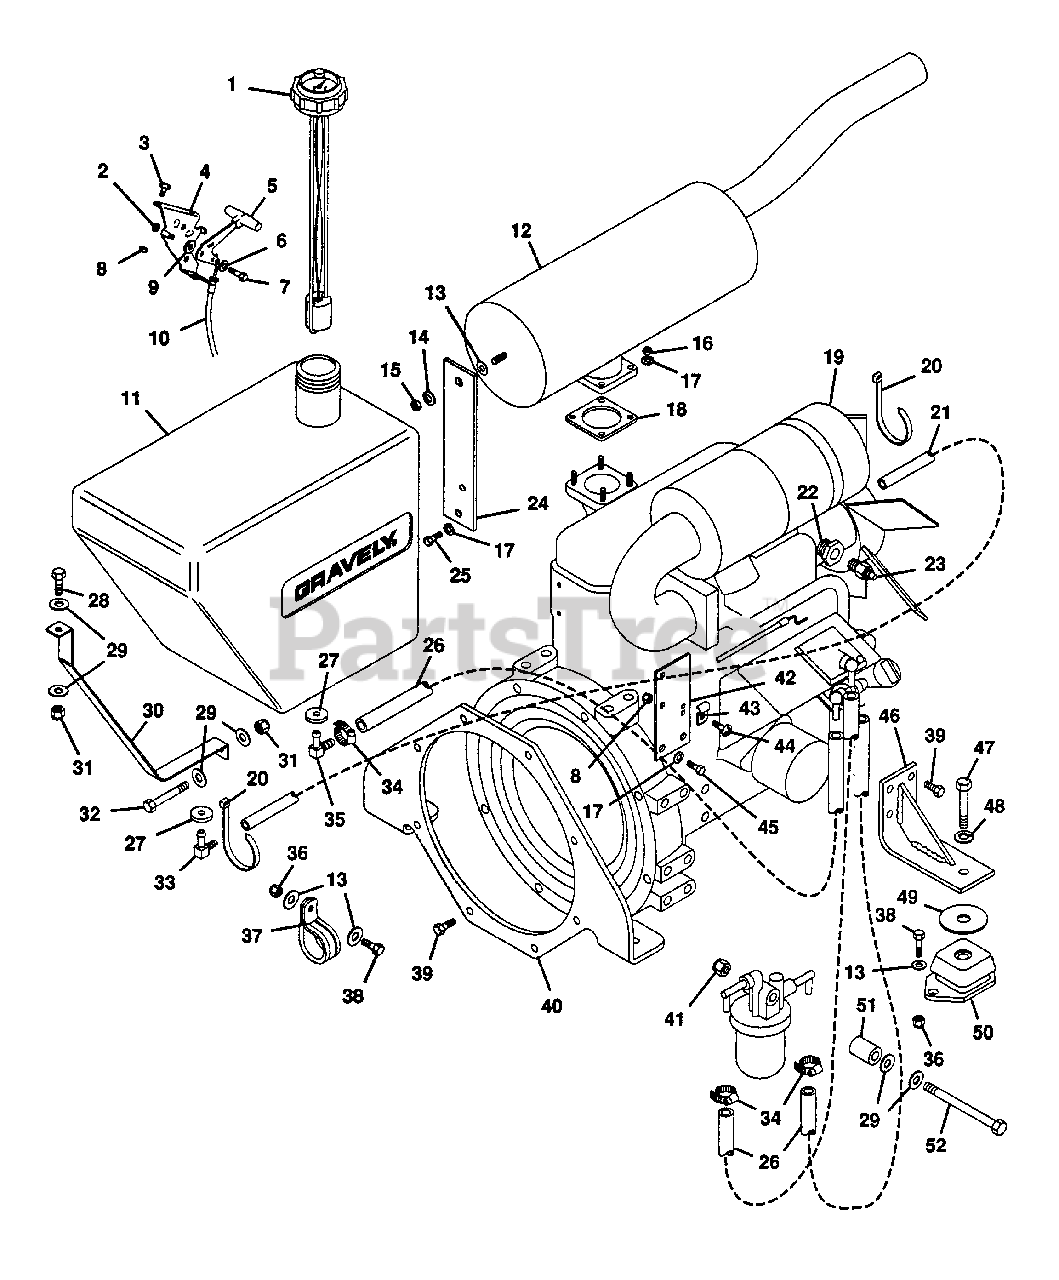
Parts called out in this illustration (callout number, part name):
1	Gauge, Fuel
2	Nut, Lock 1/4-28
3	Screw, Machine 10-24x.50 PHD
4	Bracket, Mounting L.H.
5	Assembly, Knob and Lever
6	Washer, Spring
7	Bolt, Hex 1/4-28x.75
8	Nut, Lock 10-24
9	Washer, Friction
10	Assembly, Conduit
11	Tank, Fuel
12	Muffler, Yanmar
13	Washer, Flat .406x.812x.065
14	Washer, Lock 3/8 Reg.
15	Nut, Hex 3/8-16
16	Nut, Hex M8 x 1.25
17	Washer, Lock 5/16 Reg.
18	Gasket, Exhaust
19	Engine, Yanmar
20	Tie Wrap, Black
21	Hose, Fuel .125 ID
22	Adapter, Temperature Sender
23	Sender, Temperature
24	Brace, Muffler
25	Bolt, Hex M8 x 1.25 16mm
26	Line, Fuel .5 OD x .25 ID
27	Bush., Flg. .375x1.06x.625 Rb.
28	Bolt, Hex 5/16-18x2.00
29	Washer, Flat .344x.688x.065
30	Strap, Gas Tank
31	Nut, Lock 5/16-18
32	Bolt, Hex 5/16-18x.75
33	Fitting, Tank
34	Clamp, Hose
35	Fitting, Tank
36	Nut, Lock 3/8-16
37	Clamp, Steel 1.00
38	Bolt, Hex 3/8-16x1.00
39	Bolt, Hex M10 x 1.5 20mm
40	Mount, Engine
41	Nut, Lock 5/16-18
42	Bracket, Control
43	Clip
44	Screw, Machine 10-24x.625 PHD
45	Bolt, Hex M8x1.25 20mm
46	Weldment, Engine Mount
47	Bolt, Hex M12x1.50 35mm
48	Washer, Lock 1/2 Reg.
49	Washer, Snubbing
50	Mount, Engine
51	Stop, Chute
52	Bolt, Hex 5/16-18x3.50
NS	Wrench, Fuel Filter
